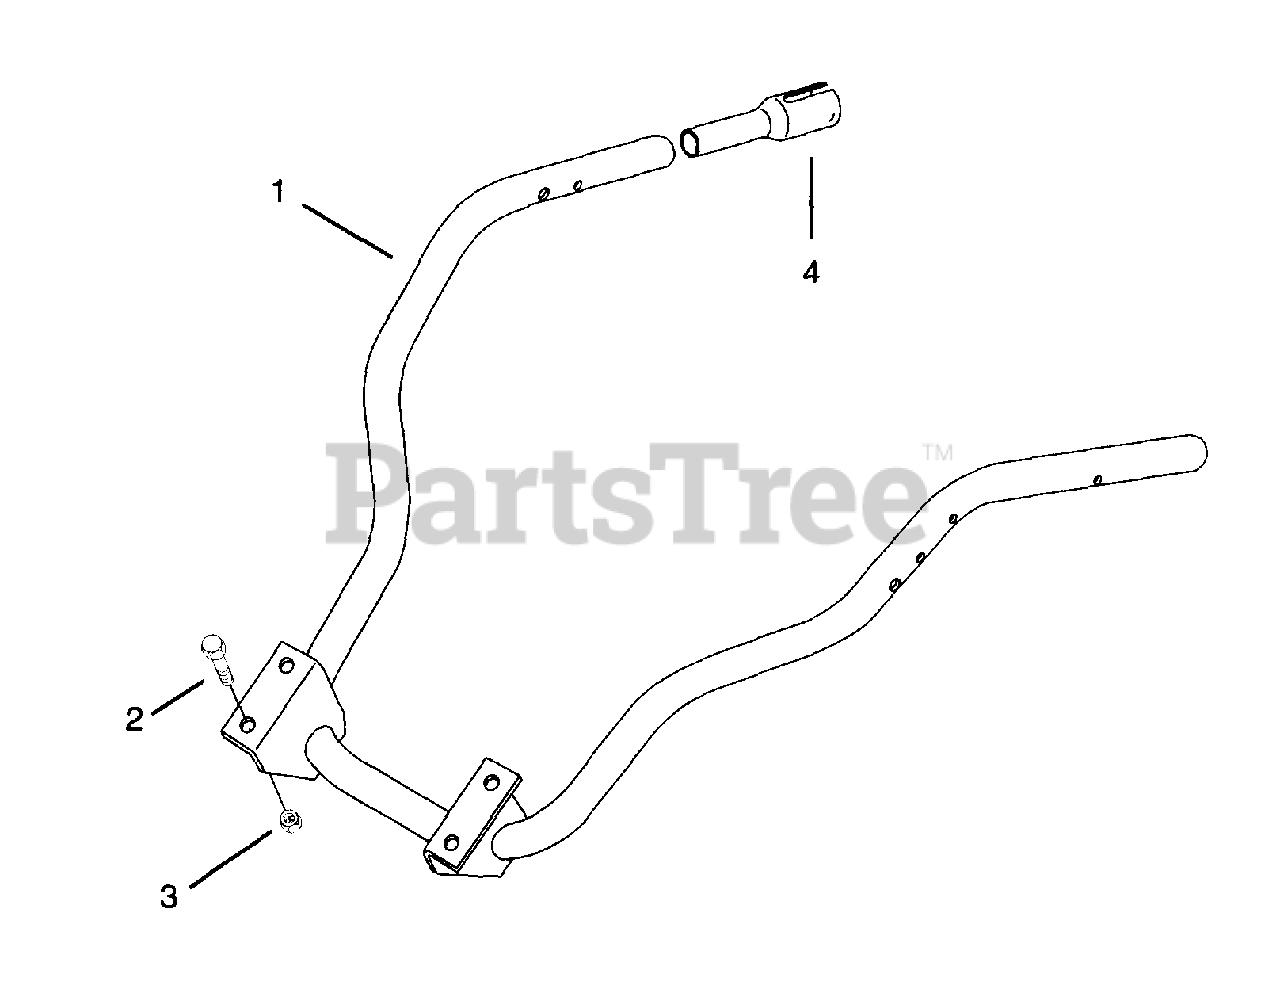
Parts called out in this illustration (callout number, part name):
1	Weldment, Handlebar
2	Bolt-Hex .38-16 x 1.25 Grade 8
3	Nut-Locking-Center .375-16 Grade 2
4	Insert, Handlebar
